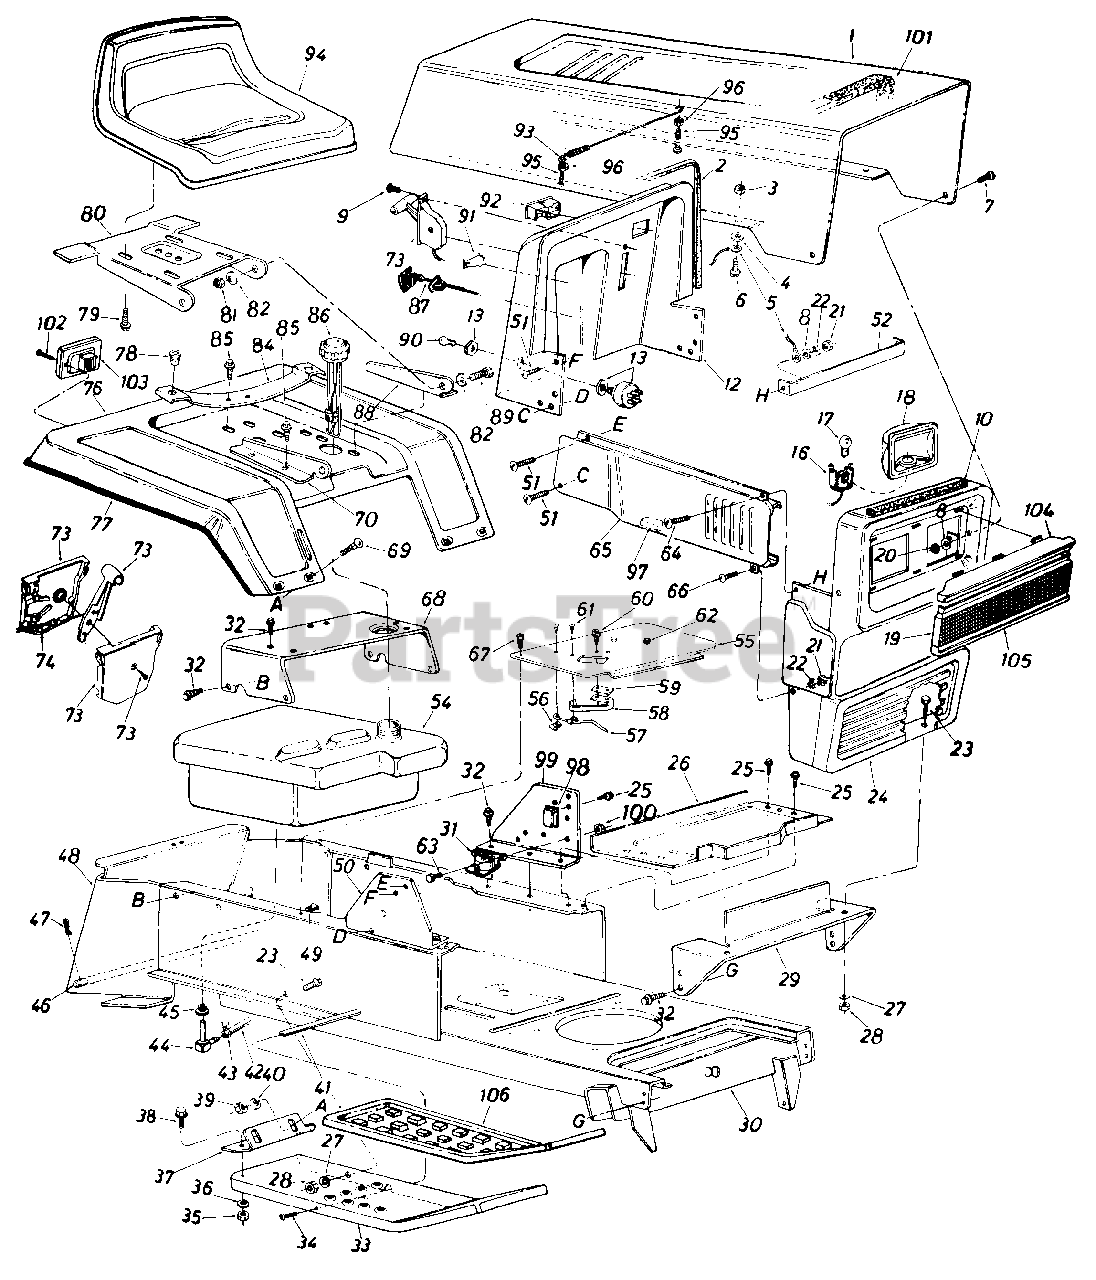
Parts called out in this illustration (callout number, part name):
1	Hood
2	Trim Strip 27" Lg.
3	Hex Sems Nut #10-24 Thd.
4	Fl-Wash. .20" I.D. x .41" O.D.
5	Hood Stop
6	Truss Hd. Mach. Scr. #10-24 x.50" Lg.
7	Hex Bolt 1/4-20 x .62" Lg.
8	Fl-Wash. 1/4" I.D.
9	Truss Mach. AB-Tap Scr. #10 x .50" Lg.
10	Foam Strip 3/8" x 1" x 14"
12	Dash Ass'y.
13	Ignition Switch
16	Socket
17	Lamp
18	Headlight Housing
19	Headlight Bezel
20	Hex L-Nut 1/4-20 Thd.
21	Hex Nut 1/4-20 Thd.
22	L-Wash. 1/4" I.D.
23	Hex Bolt 5/16-18 x .75" Lg.
24	Grille
25	Hex Wash. Hd. Scr. 1/4" x .50" Lg.
26	Battery Plate
27	L-Wash. 5/16" I.D.
28	Hex Nut 5/16-18 Thd.
29	Grille Mounting Bracket
30	Lower Frame Ass'y.
31	Solenoid
32	Hex Thd. Rolling Scr. 5/16-24 x .75" Lg.
33	Running Board R.H.
34	Truss Mach. Scr. 5/16-18 x .75" Lg.
35	Hex Nut 5/16-18 Thd.
36	Bell-Wash. .34" I.D. x .87" O.D.
39	Hex Nut 1/4-20 Thd.
40	L-Wash. 1/4" I.D.
41	Running Board Rod
42	Fuel Line 40" Lg.
43	Hose Clamp 3/8"
44	90ø Nipple
45	Bushing
46	Hitch Rod
47	Internal Cotterpin
48	Hitch Plate
49	Speed Nut
50	Dash Support Brkt. R.H.
51	Hex Wash. Hd. Tap Scr. 1/4 x.75" Lg.
52	Tie Strap
54	Fuel Tank
55	Transmission Cover Ass'y.
56	Speed Nut #10-24 U-Type
57	Shift Lever Spring
58	Switch Spring
59	Insulator Plate
60	Hex Wash. Hd. AB-Tap Scr. #18 x .50
61	Truss Mach. Scr. #10 x .50" Lg.
62	Snap Bushing
63	Hex Bolt 1/4-20 x .50" Lg.
64	Truss Hd. Scr. 1/4-20 x .75" Lg.
66	Truss Mach. Scr. 1/4-20 x .50" Lg.
67	Truss Mach. "B" Tap Scr. #10 x .50" Lg.
68	Seat Mounting Channel
69	Carriage Bolt 1/4-20 x .50" Lg.
70	Seat Bracket R.H.
73	Throttle Control Box Ass'y.
74	Throttle Control Wire
76	Rear Fender
77	Trim Strip 81"
78	Grommet
79	Hex Wash. Hd. AB-Tap Scr. 3/8 x .75" Lg.
80	Seat Pivot Bracket
81	Hex Cent. L-Nut 5/16-18 Thd.
82	Belleville Wash. .34" I.D. x .88" O.D.
84	Seat Spring
85	Hex Wash. Hd. Self-Tap Scr. 5/16-18 x .50" Lg.
86	Gas Cap w/Gauge
87	Choke Control Comp.
88	Seat Bracket L.H.
89	Hex Bolt 5/16-18 x .75" Lg.
90	Ignition Key
91	Light Switch
92	Ammeter
93	Hood Spring
94	Seat Ass'y.
95	Hex Screw #10-24 x 1.0" Lg.
97	Rubber Strip 1/2" Sq. x 21/2 " Lg .
98	Circuit Breaker
99	Dash Support Brkt. L.H.
100	Hex Sems Nut 1/4-20 Thd.
101	PVC Foam
102	Truss Hd. AB-Tap Scr. #6 x .62" Lg.
103	Taillight
104	Upper Frame For Bezel
105	Lower Frame For Bezel
106	Foot Pad
